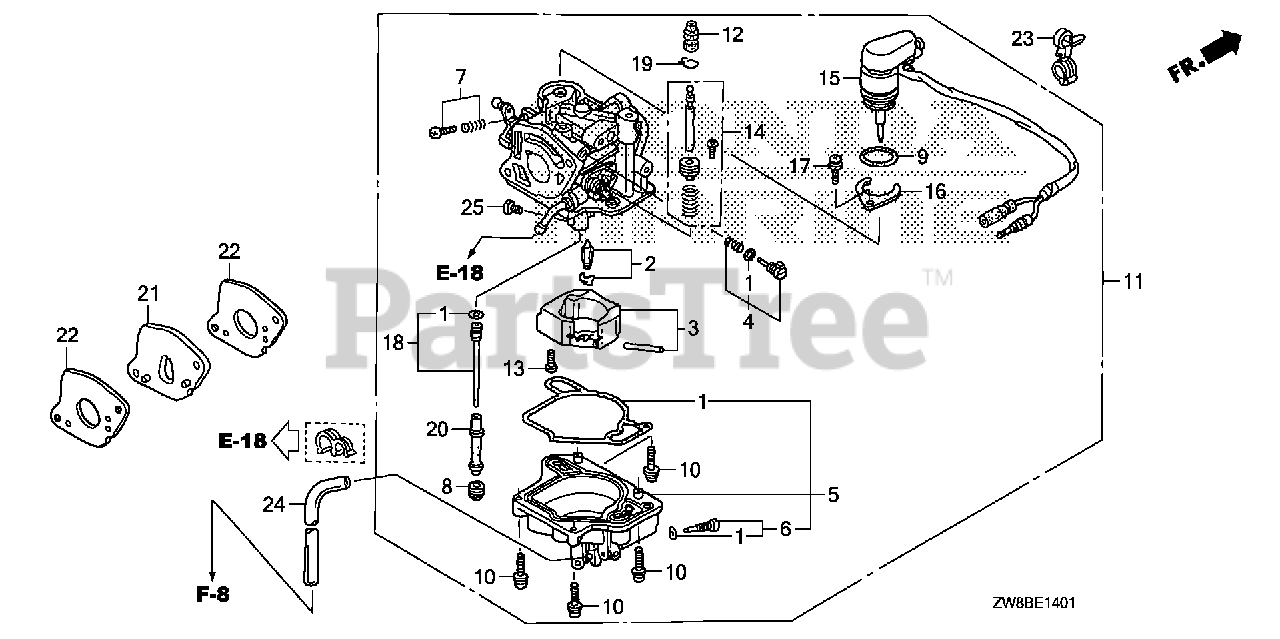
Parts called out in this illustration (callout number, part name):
1	GASKET SET
2	VALVE SET, FLOAT
5	CHAMBER SET, FLOAT
6	SCREW SET, DRAIN (CARBURETOR NO.)
7	SCREW SET
8	SCREW, PLUG
9	O-RING, BYSTARTER
10	SCREW-WASHER
11	CARBURETOR ASSY. (BJ02B D)
13	SCREW, PAN
14	PLUNGER SET, ACCELERATOR PUMP
15	BYSTARTER ASSY., AUTO
16	PLATE, SETTING
17	SCREW-WASHER
18	JET SET (#45)
19	CLIP, TUBE
20	NOZZLE, MAIN
21	INSULATOR, CARBURETOR
22	GASKET, CARBURETOR
23	CLIP, TUBE (135MM) (BLACK)
24	BULK HOSE, VINYL (4X7X8000) (95003-07(95003-07001-60M) (CARBURETOR NO.)
25	JET, MAIN (#98)
25	JET, MAIN (#102)
25	JET, MAIN (#105)
25	JET, MAIN (#108)
